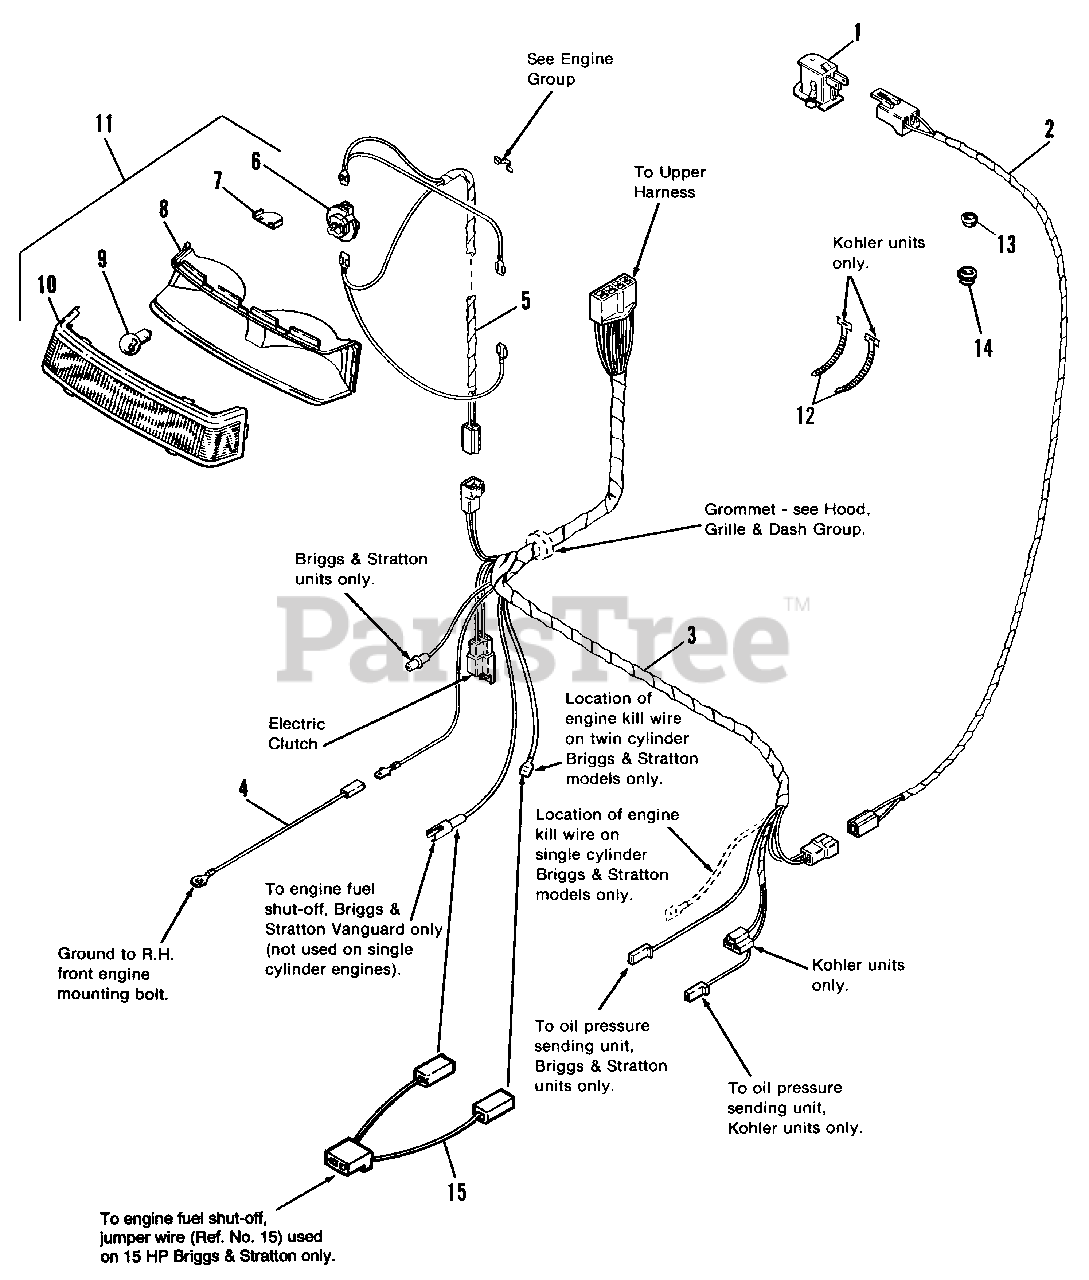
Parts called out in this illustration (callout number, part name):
1	SWITCH, Seat, Operator Present
2	WIRE ASSY., Seat Switch
3	HARNESS ASSY., Lower (12.5, 15 & 16 HP Briggs & Stratton)
3	HARNESS ASSY., Lower (14 HP Kohler))
4	WIRE ASSY., Engine Ground
5	WIRE ASSY., Headlight
6	SOCKET, Bulb
7	HEAT SHIELD
8	BEZEL, Headlight
9	BULB, Headlight, 12.8V
10	LENS, Headlight
11	HEADLIGHT ASSY. (Incl. Ref. Nos. 6-10)
13	BUSHING, Snap, Small
14	BUSHING, Snap, Large (14 HP Kohler only)
15	WIRE ASSY., Jumper (15 HP Briggs & Stratton only)
